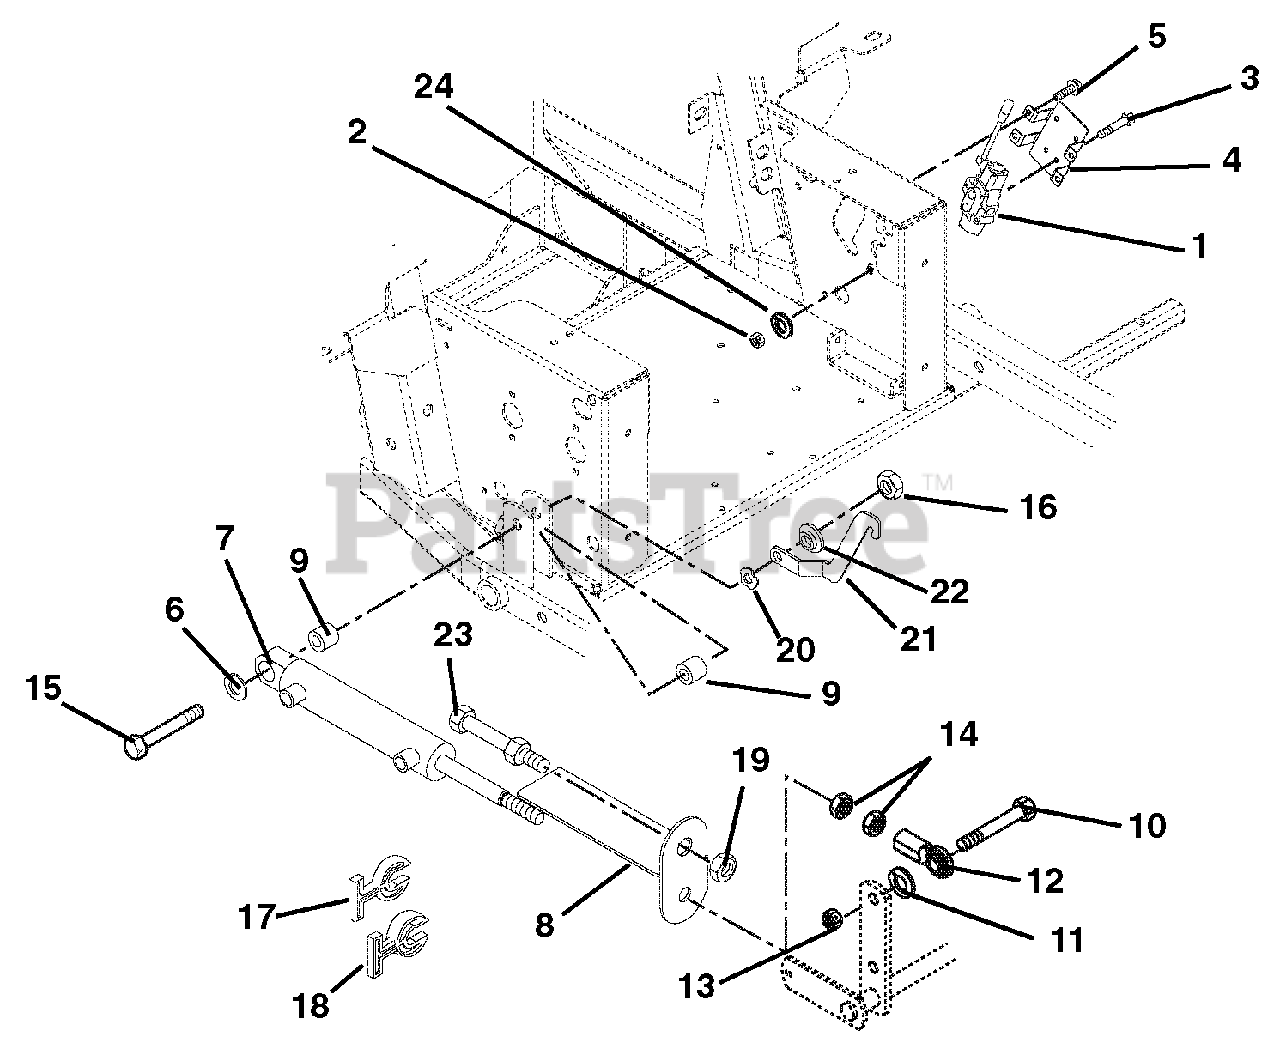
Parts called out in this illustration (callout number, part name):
1	VALVE - HYDRAULIC LIFT
2	@NUT-LK-CTR .31-18 YWZC
3	@BLT-HEX .31-18X2.00 GR5 YWZC
4	BRACKET - VALVE MOUNTING
5	@SCR-TAP .38-16X.50 HWH TR YWZ
6	WSHR-FL-STL .515X1.625X.250 YZ
7	CYLINDER, LIFT
8	CUT INDICATOR/GUARD - BLACK
9	BUSHING, .516X1.000X1.050 LG
10	BLT-HEX .62-11X2.25 YWZC GR8
11	@WSHR-LK .62X.156 REG YWZC
12	ROD END, 5/8 RH - FEMALE
13	@NUT-LK-CTR .62-11 YWZC
14	NUT-JAM .625-18 YWZC
15	@BLT-HEX .50-13X3.75 GR5 YWZC
16	@NUT-LK-TOP-FLG .50-13 YWZC
17	STOP, CYLINDER .34 THK
18	STOP, CYLINDER .680 THK
19	NUT-JAM .75-16 YWZC
20	WASHER-WAVE .760X1.120X.080
21	LATCH, FOOTBOARD HOOK
22	BSHG-FLG .515X.750X.285X1.120
24	@WSHR-LK .31X.078 REG YWZC
